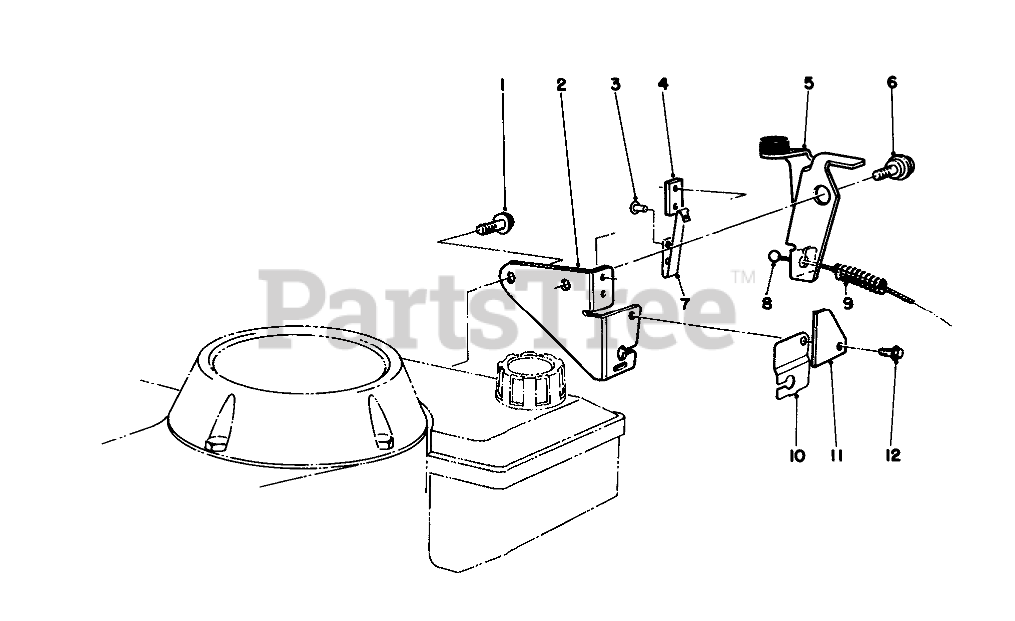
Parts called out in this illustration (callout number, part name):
1	THO FORM SCREW M6 X 1
2	Plate-Mounting
3	Rivet
4	Strap-Insulation
5	BRAKE PLATE ASM
6	Screw-Shoulder
7	STRAP-GROUND
8	BRAKE CABLE
9	FRONT PLATE ASM
10	CABLE CLAMP
11	STOP-GROUND STRAP
12	SCREW
